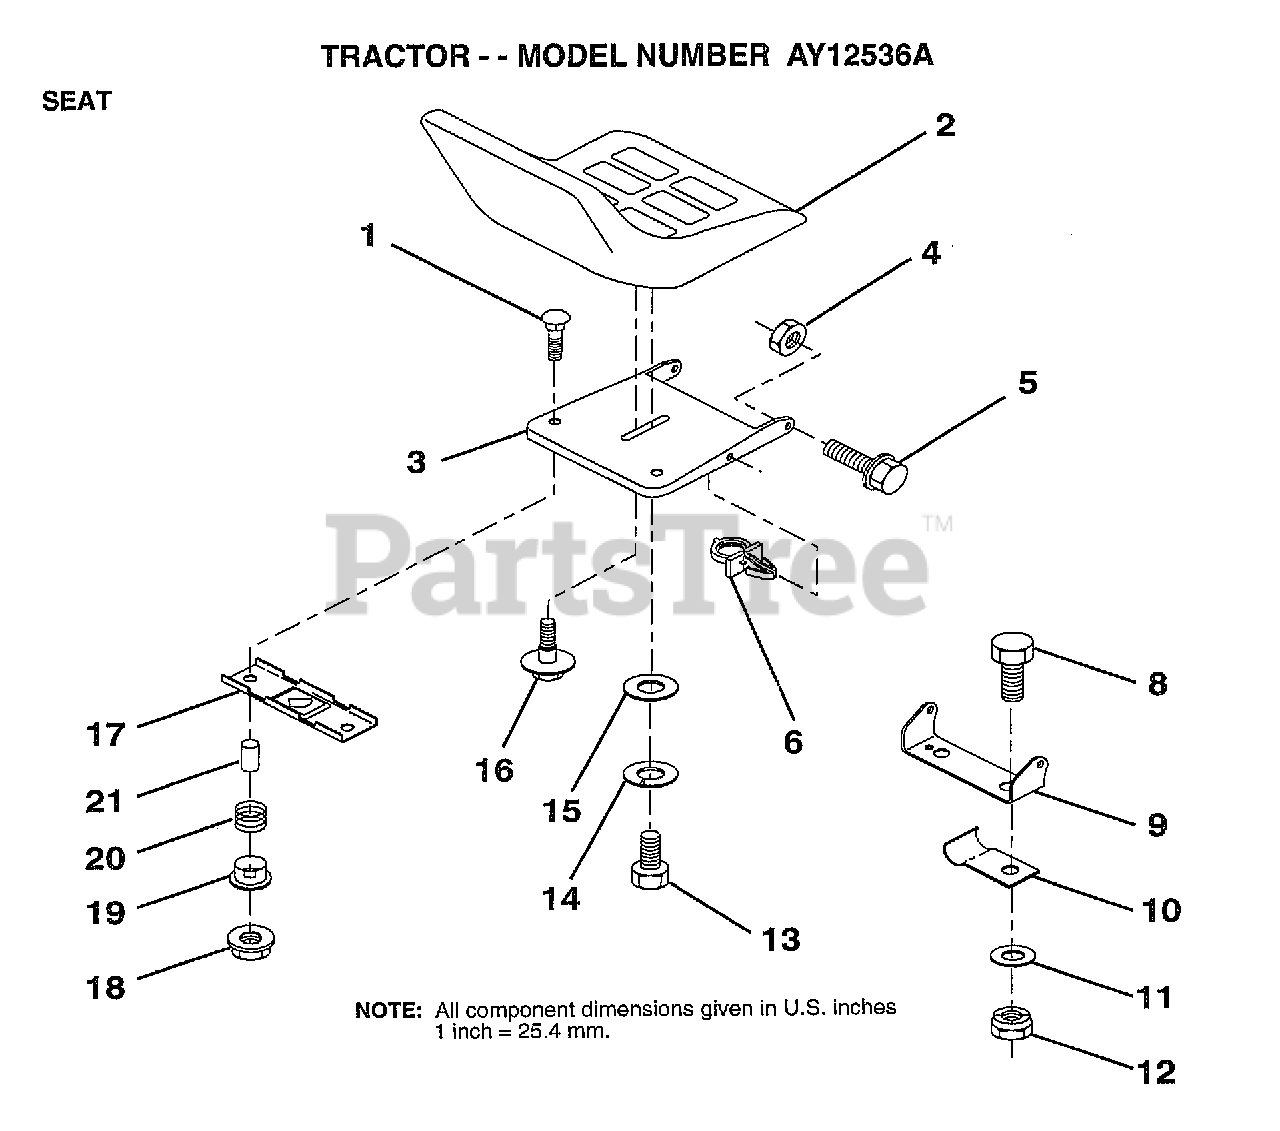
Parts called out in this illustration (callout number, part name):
4	NUT
5	BOLT.SHLD.5/16-18
6	CLIP.PUSH-IN.HING
8	BOLT
9	BRACKET PVT SEAT
10	"CLIP,INSULATOR"
11	WASHER
12	NUT
13	BOLT
14	LOCKWASHER
15	WASHER
16	"BOLT,SHOULDER"
17	BRKT SWITCH
19	BUSHING
20	SPRING
21	SPLIT SPACER
